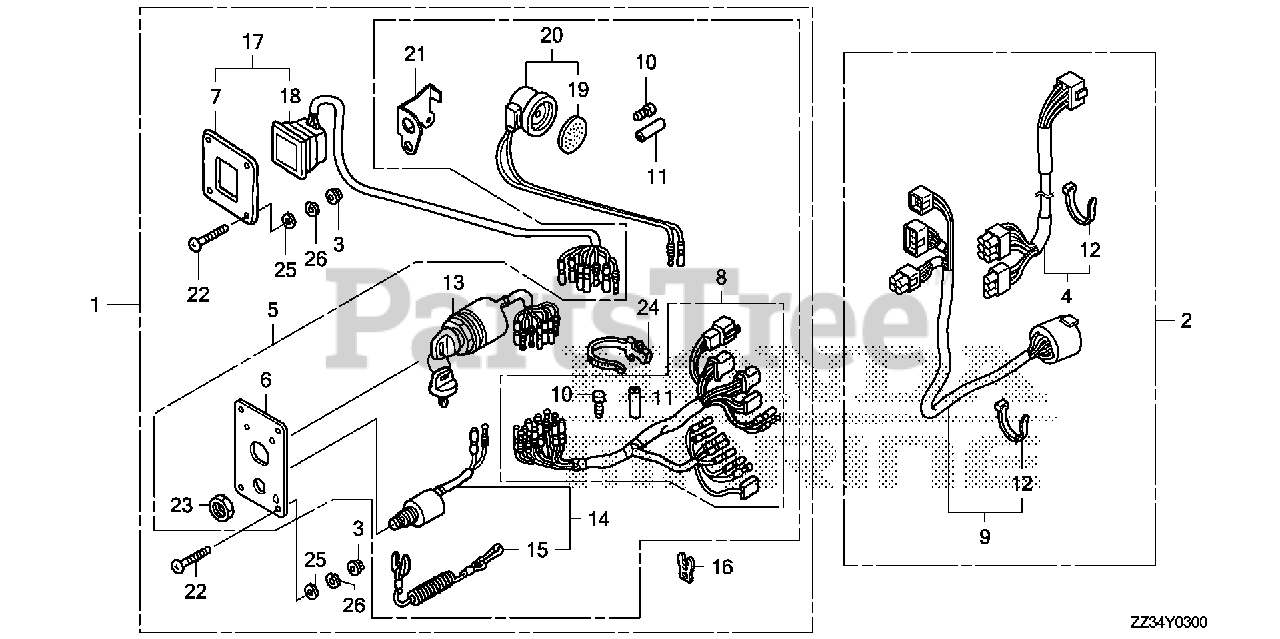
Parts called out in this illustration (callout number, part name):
1	PANEL KIT, SWITCH (4-LED) (B)
2	CABLE SET, PANEL INDICATOR (20FT)
2	CABLE SET, PANEL INDICATOR (25FT)
2	CABLE SET, PANEL INDICATOR (30FT)
3	NUT, FLANGE (5MM)
4	WIRE ASSY., INDICATOR (20FT)
4	WIRE ASSY., INDICATOR (25FT)
4	WIRE ASSY., INDICATOR (30FT)
5	PANEL ASSY., SWITCH
6	PANEL, CONTROL
7	PANEL, CONTROL
8	HARNESS ASSY., SWITCH PANEL
9	CABLE ASSY., SWITCH PANEL (25FT) (NHK MEC)
9	CABLE ASSY., SWITCH PANEL (20FT)
9	CABLE ASSY., SWITCH PANEL (25FT)
9	CABLE ASSY., SWITCH PANEL (30FT)
10	PLUG, CONNECTOR (INNER)
11	PLUG, CONNECTOR (OUTER)
12	TIE, CABLE (2.4X92) (NATURAL)
13	SWITCH ASSY., COMBINATION
14	SWITCH ASSY., EMERGENCY STOP
15	WIRE, EMERGENCY
16	CLIP, EMERGENCY LOCK
17	PANEL ASSY., INDICATOR (4-LED)
18	LAMP ASSY., INDICATION (4-LED)
19	PLATE, TURN SIGNAL BUZZER
20	BUZZER, WARNING
21	BRACKET, BUZZER
22	SCREW, PAN (5X40)
23	NUT, HEX. (16MM)
24	BAND, WIRE HARNESS (150MM) (NATURAL)
25	WASHER, PLAIN (5MM)
26	WASHER, SPRING (5MM)
